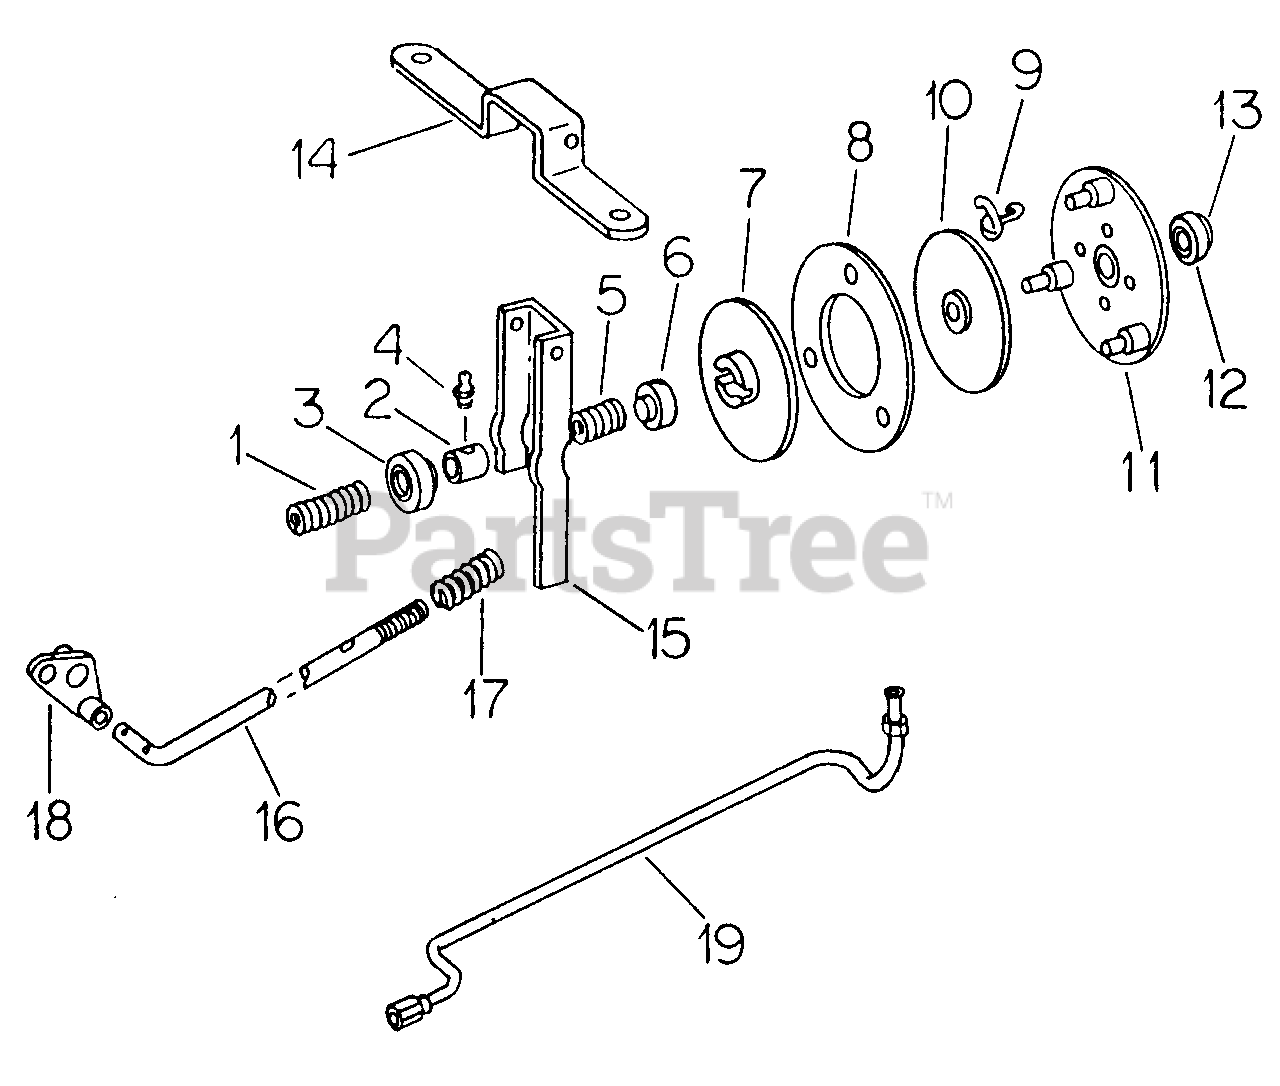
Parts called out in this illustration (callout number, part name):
1	Spring, Loading
2	Bushing, Lubricating
3	Bearing, Throwout Ball
4	Fitting, 1/4-28 Taper Drive Thread Lube
5	Spring, Teasing
6	Spacer, Spring
7	Hub Assy, Pressure Plate
8	Disc, Clutch Friction
9	Spring, Driving Disc
10	Hub Assy, Pressure Plate Locating
11	Plate Assy, Driving
12	Hub Assy, Pilot
13	Bushing, Ball
14	Hanger Assy, Clutch Lever
15	Lever, Release
16	Rod, Clutch Release
17	Spring, Release Rod
18	Arm, Clutch & Brake Pedal
19	Tube Assy, Return
